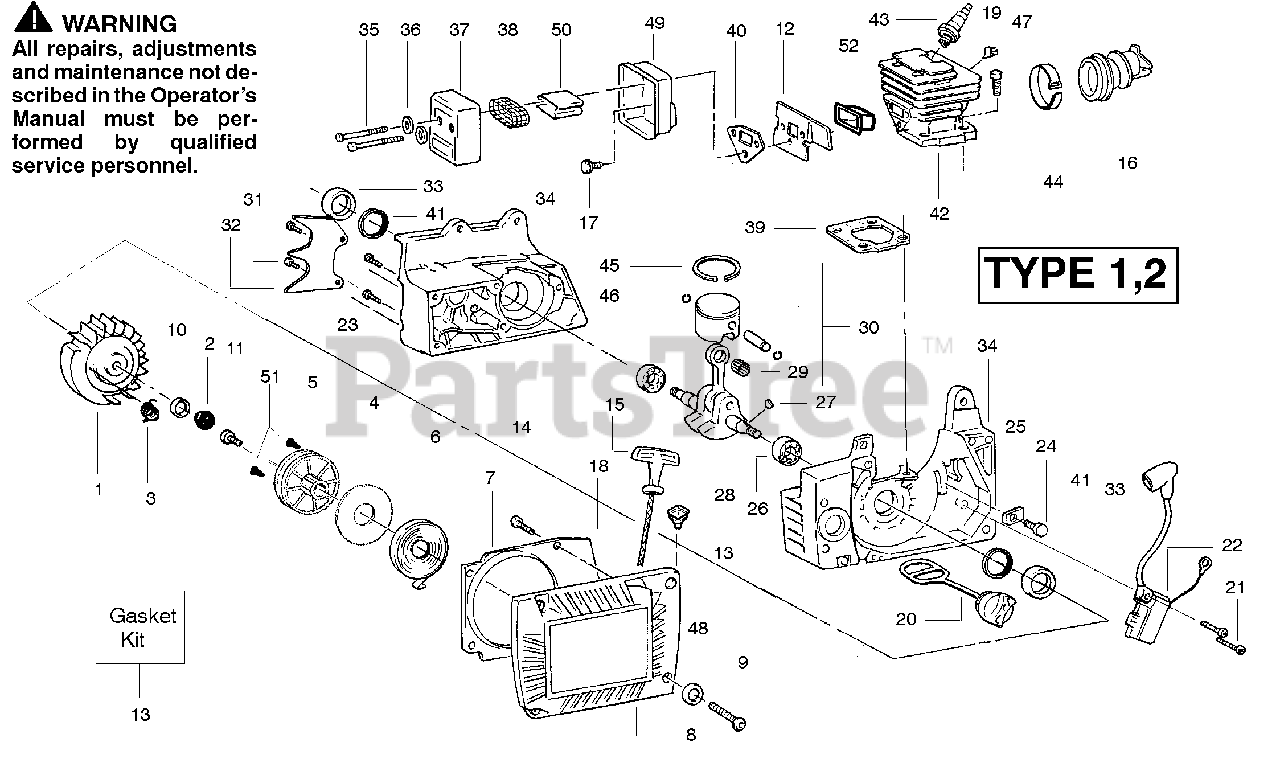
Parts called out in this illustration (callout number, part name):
1	Flywheel Ass’y. Kit
3	Spring-Starter Dog
5	Starter Pulley
6	Starter Spring
8	Fan Housing Ass’y.
10	Washer-Conical
12	Muffler Back Plate
13	Kit - Gasket
15	Starter Handle
20	Oil Cap Ass’y.
21	Screw
22	Ignition Module
26	Crankshaft Bearing
28	Crankshaft & Rod Ass’y.
29	Piston Pin Bearing
30	Piston Kit
33	Crankshaft Seal
34	Crankcase Ass’y.
37	Muffler Cover
38	Spark Arrestor Screen
40	Muffler Gasket
42	Cylinder Ass’y.
43	Spark Plug (RCJ-6Y)
44	Clamp Ass’y.
50	Muffler Diffuser
52	Exh Port Insulator
